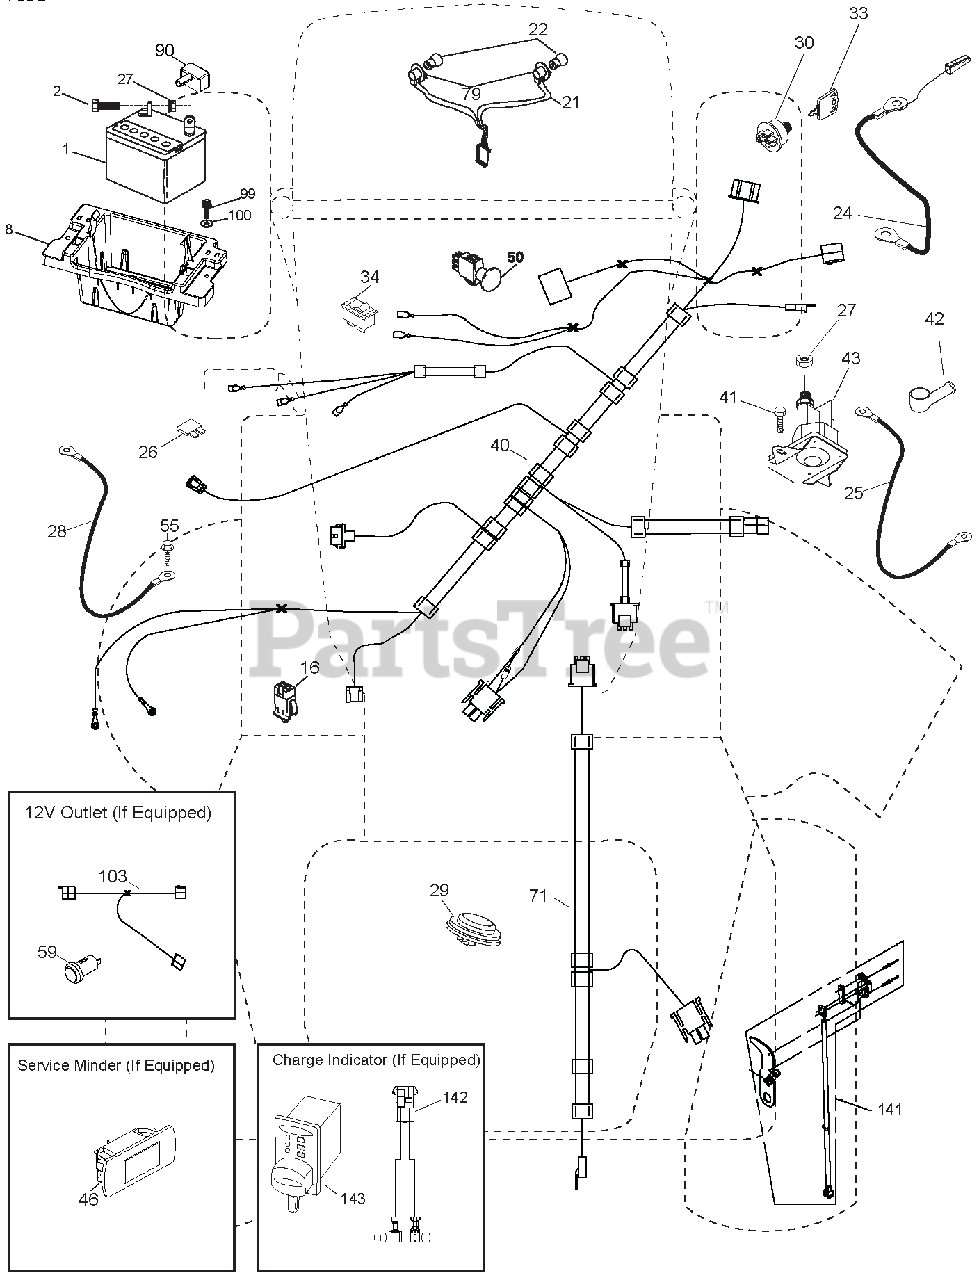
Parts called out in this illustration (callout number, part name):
1	BATTERY.12.VOLT.28.AMP.WET
2	BOLT.HEX.HD.1/4-20UNC X 3/4
8	BOX.BATTERY.MOUNT.FRONT.LT
16	SWITCH.INTERLOCK.NONO.GRAY
21	HARNESS ASM.LIGHT.22"(4152J)
22	BULB.LIGHT.#1156
24	CABLE.BTRY.PSWRE.DSH SOL.8"TEX
25	CABLE.STARTER
26	FUSE.20 AMP.
27	Nut, Keps Hex 1/4-20 unc
28	CABLE.GROUND.21"BLK.6 GA.90T
29	SWITCH.SEAT.DELTA.OPC.9LB.
30	SWITCH.IGN.DLTA.P-IN.ROS
33	KEY/CHAIN.BLISTER PACK.GEN.USA
34	SWITCH.LIGHT/RESET.B/B/RED.
40	HARNESS.IGN.DASH.HUSQ/PRED.
41	Screw 1/4-20 x 1/2
42	COVER.TERMINAL.RED
43	SOLENOID.W/BRASS PLUNGER.2005
46	HOUR METER
50	SWITCH.PTO.8 TERMINAL.BLACK
55	SCREW.5/16-18X3/4.SMGML.TAP/R
71	HARNESS.IGN.CHASSIS.TEX
79	SOCKET ASM.BULB.TWISTLOCK
90	COVER TERMINAL BATTERY FR. TEX
91	STRAP.BATTERY.MOUNT.FRONT
99	SCREW.HEXWSH.THDROL.1/4-20X3/4
100	WASHER.9/32 X 7/8 X 16GA.
141	KIT G700/G730 ROS
